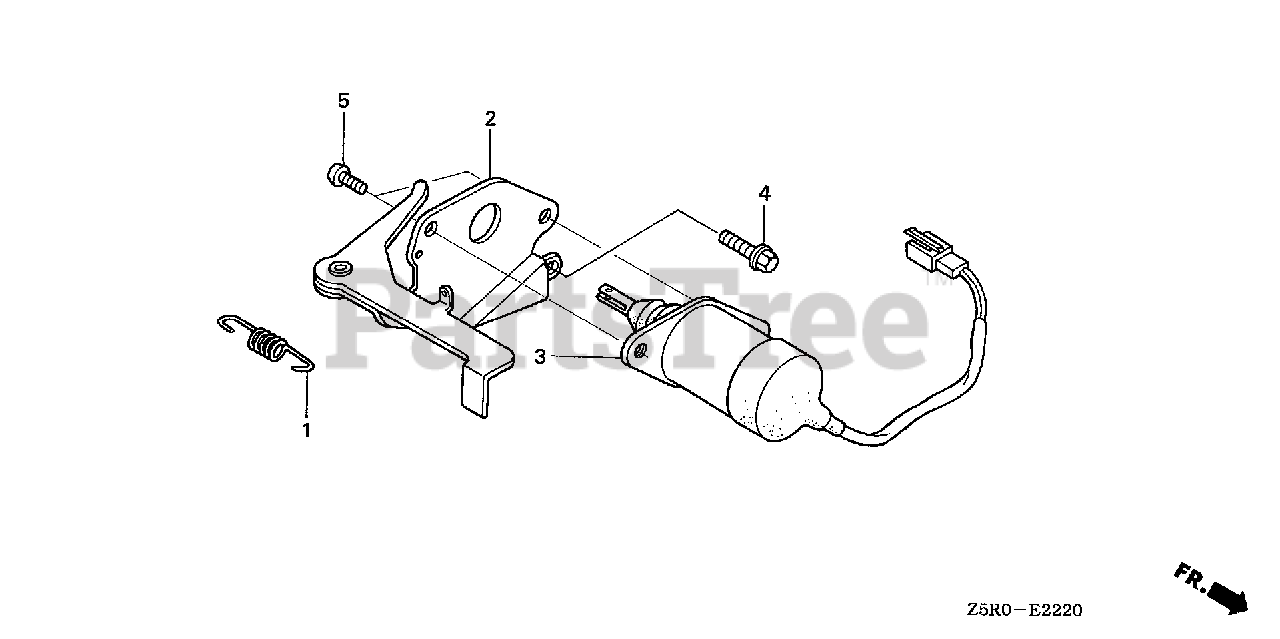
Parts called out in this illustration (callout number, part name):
1	SPRING, CHOKE RETURN
2	LEVER, THROTTLE
3	SOLENOID ASSY.
4	BOLT, FLANGE (6X12) (CT200)
5	SCREW, PAN (5X8)
